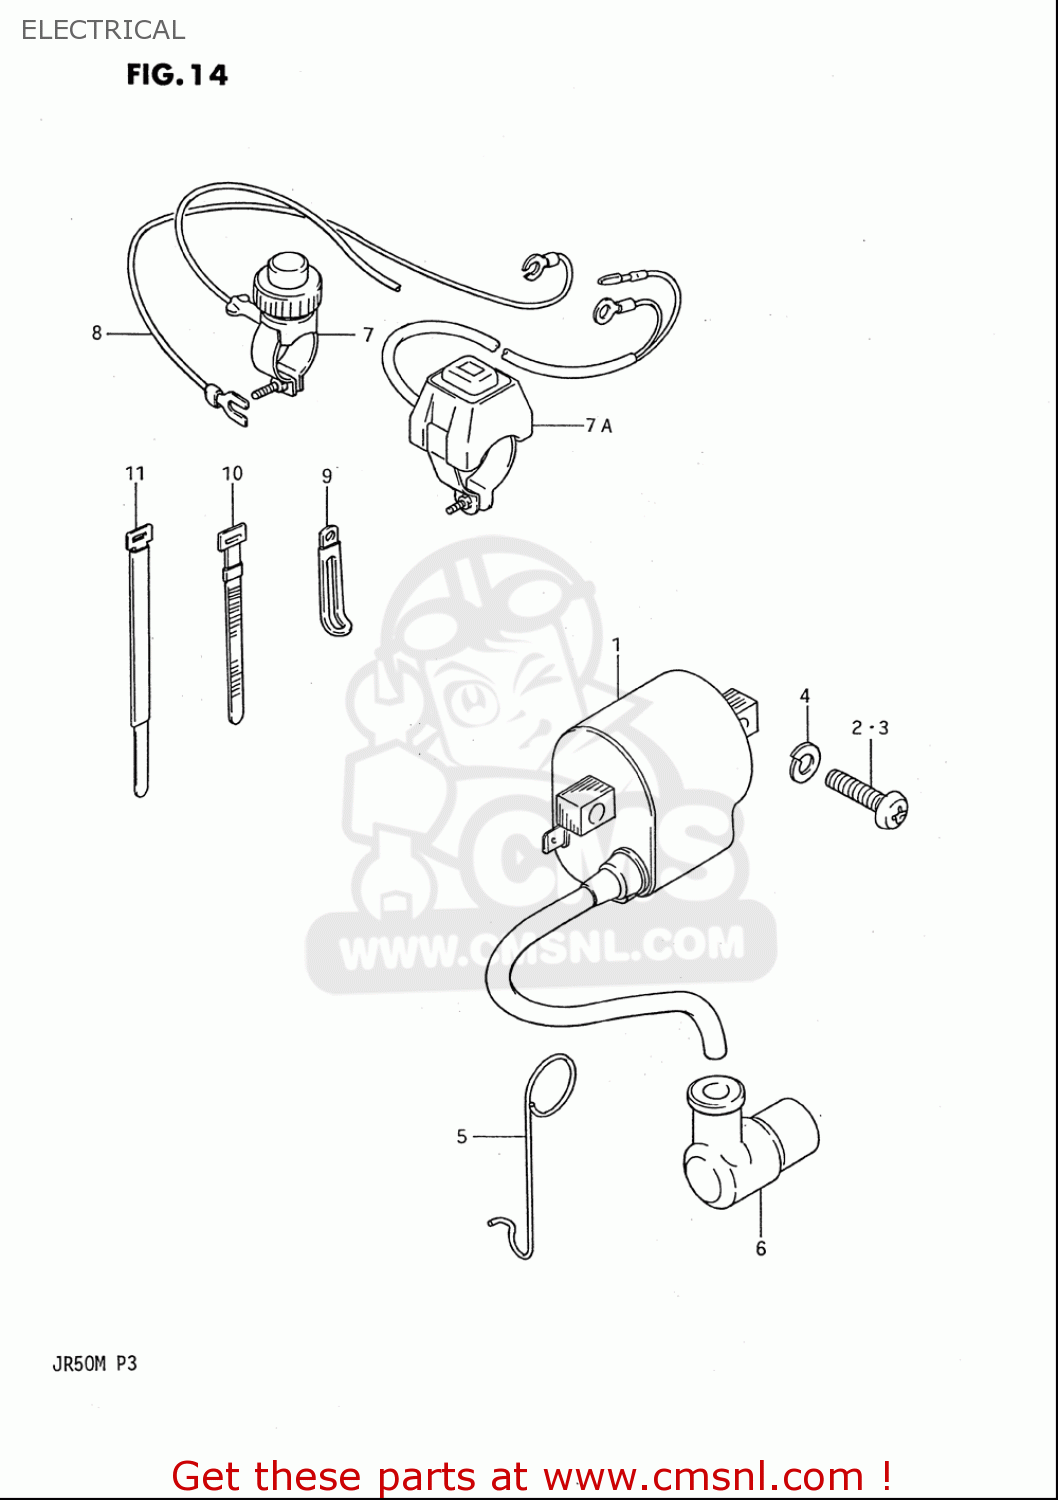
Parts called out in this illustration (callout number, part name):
1	UNIT & COIL ASSY,IGNITION
2	SCREW
3	SCREW
4	WASHER,LOCK
5	CLIP
6	CAP,SPARK PLUG
7	SWITCH ASSY,ENGINE STOP
7A	SWITCH ASSY,ENGINE STOP
9	CLAMP(L:65)
10	CLAMP(L:120)
11	CLAMP
